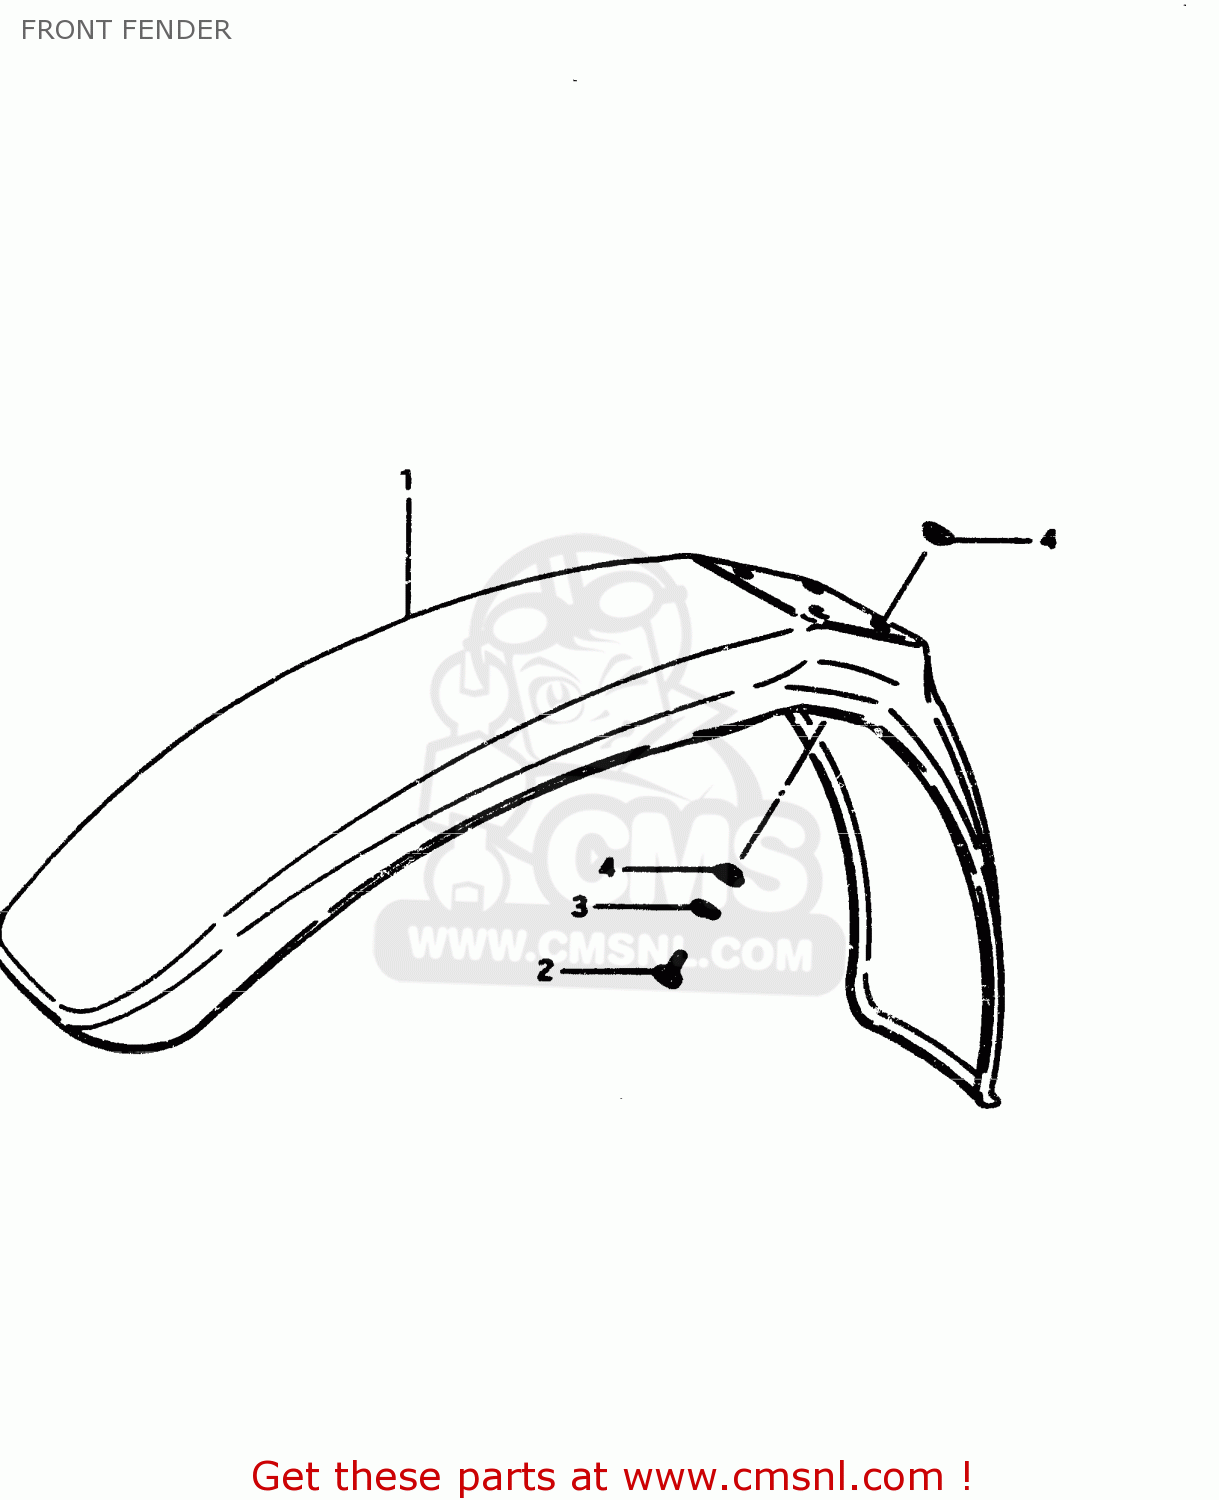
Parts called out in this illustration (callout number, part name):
1	FENDER,FRONT
2	BOLT, UPPER
3	LOCK WASHER
4	SPACER
